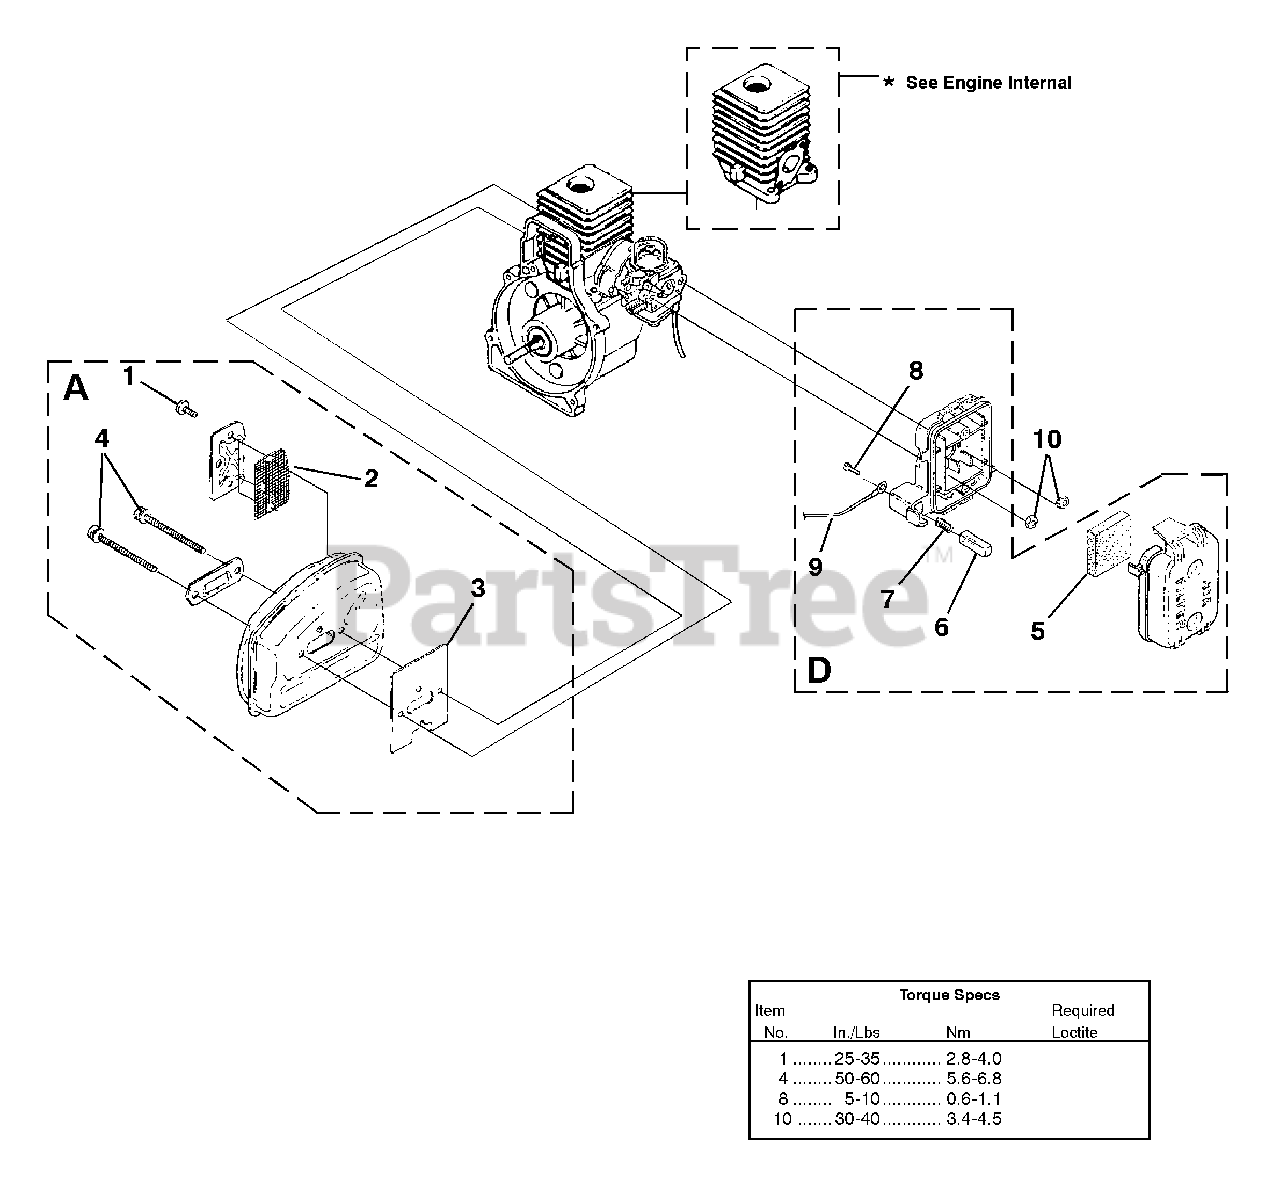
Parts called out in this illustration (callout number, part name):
1	SCREW, Taptite- (8-32 X 3/8")
2	SCREEN-Spark
3	GASKET-Muffler
4	SCREW, Truss Hd. - (10-24 X 2.188")
5	FILTER-Air
6	BUTTON-Switch
7	SPRING-Compression
8	SCREW-Thread Form (6-19 x 1/2")
9	LEAD-Electrical
10	NUT-Hex (10-24)
A	MUFFLER ASSY.
D	AIR FILTER KIT
